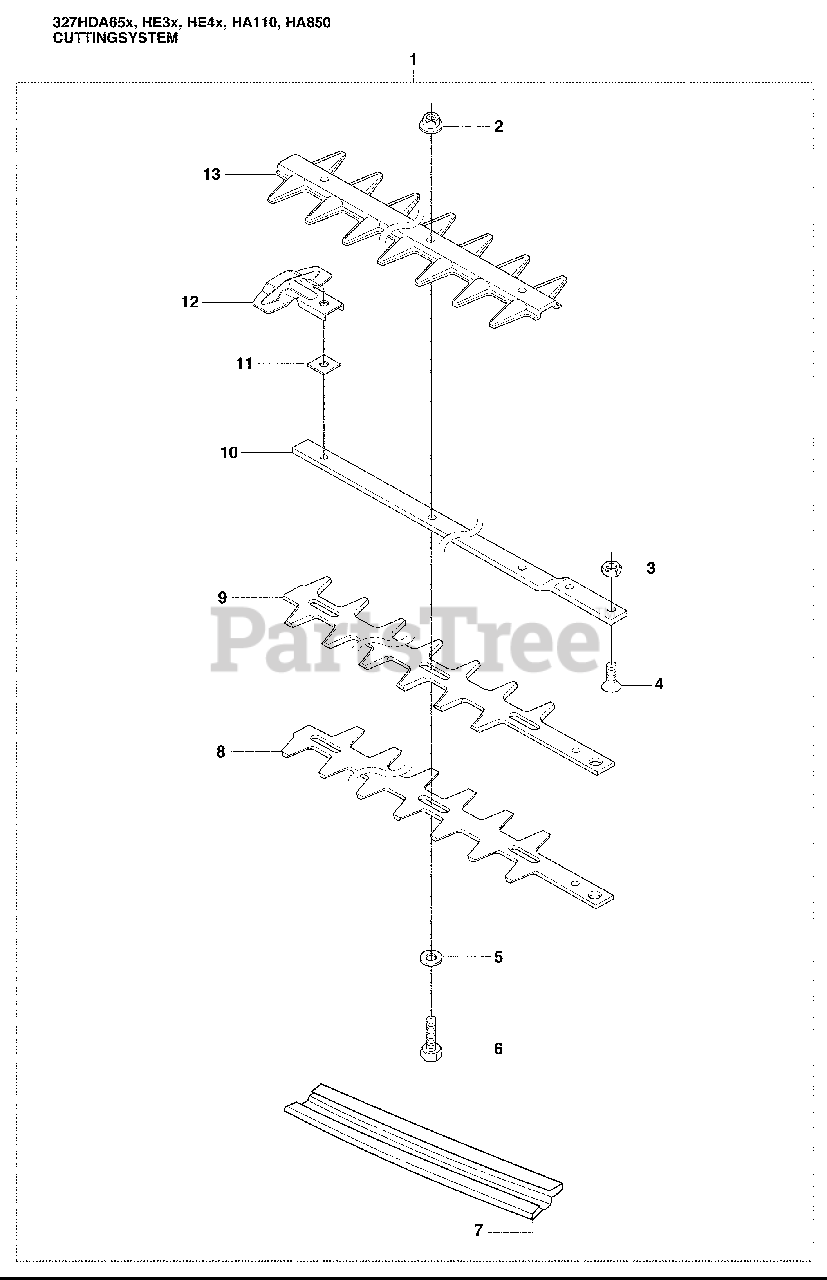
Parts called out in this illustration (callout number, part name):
11	Washer, Steel
12	Protector
13	Plate
